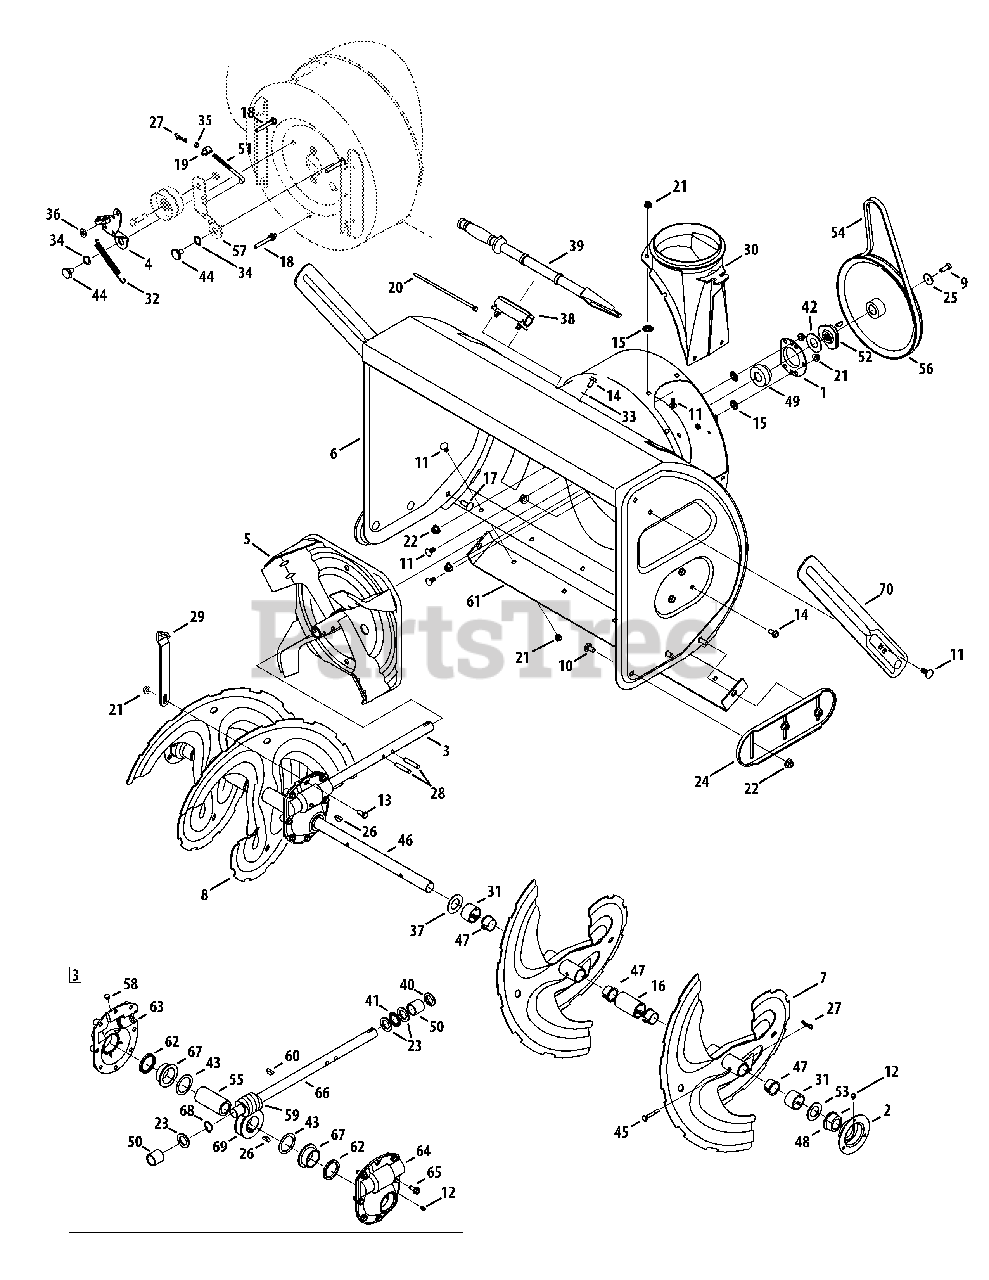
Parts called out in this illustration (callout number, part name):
1	Housing, Bearing
2	Housing, Bearing
3	Gear Box Assembly
4	Bracket Assembly, Auger Brake
5	Impeller, 16"
6	Housing, Auger
7	Spiral Assembly, LH
8	Spiral Assembly, RH
9	Screw, Hex Cap Lock, 5/16-24
10	Screw, Carriage, 3/8-16 x .75
11	Screw, Carriage, 5/16-18 x .75
12	Fitting, Lube
13	Screw, Hex Cap, 5/16-18 x 1.0 Gr5
14	Screw, 5/16-18 x .750
15	Nut, Push
16	Spacer, 1.0 x 1.5 x 2.5 Lg
17	Screw, Carriage, 3/8-16 x 1.00
18	Screw w/Stud, 5/16-18 x .4300
20	Tie Strap
21	Nut, Hex Flange Lock, 5/16-18
22	Nut, Hex Flange Lock, 3/8-16
23	Wash, Flat, .88 ID x .38 OD
24	Skid Shoe
25	Washer, Flat, .34 x 1.5 x .15 Ht.
26	Key, Woodruff, 1/4 x 3/4
27	Pin, Bow-tie Cotter
28	Pin, Spiral, 5/16 x 1.75
29	Bracket, Gear Box Support
30	Adapter, Chute, 6"
31	Spacer, 1.0 x 1.5 x 1.0 Lg
32	Spring, Extension
33	Washer, Flat, .349 x .879 .063
34	Washer, Wave, .625 x .885 x .015
35	Jam Nut, 5/16-18
36	Washer, .344 x .75 x .12
37	Washer, 1.01 x 1.86 x .06
38	Clip, Mounting
39	Tool, Clean-out
40	Seal, Oil
41	Bearing, Thrust
42	Washer, Flat, .76 x 1.49 x .06
43	Wash, Flat, 1.52ID x 2.0 OD
44	Screw, Shoulder, .625 x .17
45	Pin, Shear, .25 x 1.75
46	Shaft, Spiral
47	Bushing, Flange,
48	Bearing, Flange w/Flats
49	Bearing, Self Aligning
51	Rod, Auger Idler
52	Adapter, Pulley w/Pins
53	Spacer, 1.004 x 1.375 x .25
54	V-Belt, 1/2 x 42
55	Shaft, Gear, Worm
56	Pulley, Auger Drive, 10.0
57	Bracket, Auger Idler
59	Gear, Worm
60	Key, Hi Pro, 3/16 x 3/4
61	Plate, Shave
63	Hsg, Ass’y, Auger RH (Incl. Ref. 62 & 67)
64	Hsg, Ass’y, Auger LH (Incl. Ref. 62 & 67)
65	Screw, LD, 5/16-18 x .750
66	Shaft, Drive, Auger
67	Flange Bearing
68	External, Retaining, Ring
69	Gear, Worm, LH
70	Blade Guide
